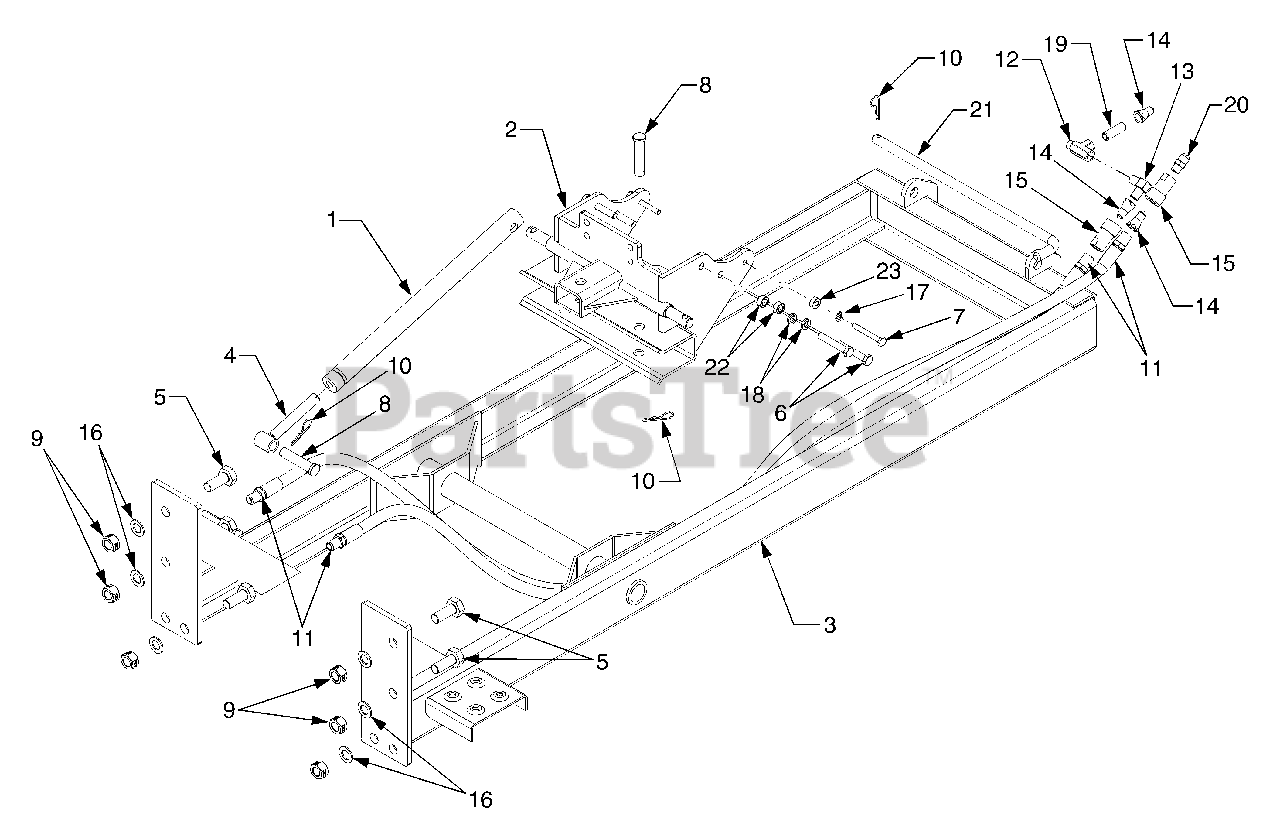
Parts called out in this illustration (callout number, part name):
1	Link, Top Adjustment
2	Bracket, Backhoe Mounting
3	Frame, Backhoe
4	Rod, Top Link Adjustment
5	Screw, Hex Cap, M20-1.5 x 50
6	Screw, Hex Cap, M12-1.75 x 75 GR8.8
7	Screw, Hex Cap, M10-1.5 x 75 GR8.8
8	Pin, Clevis, 19mm x 84mm
9	Nut, Hex Center Lock, M20 x 1.5
10	Pin, Internal Cotter
11	Hose, Hydraulic, 1/2ID x 100
12	Fitting, Tee, 3/8-18
13	Fitting, Elbow - Male
14	Coupling, Hydraulic - Male
15	Coupling, Hydraulic - Female
16	Washer, Flat, .812 x 1.38 x .1
17	Washer, Lock, 7/16
18	Washer, Lock, 1/2
19	Pipe, Straight, 3/8 NPT x 2.0
20	Fitting, Adapter - Male
21	Rod, Backhoe Pin
22	Spacer, .505 ID x .88 x .44
23	Spacer, 39 ID x .850 x .375
